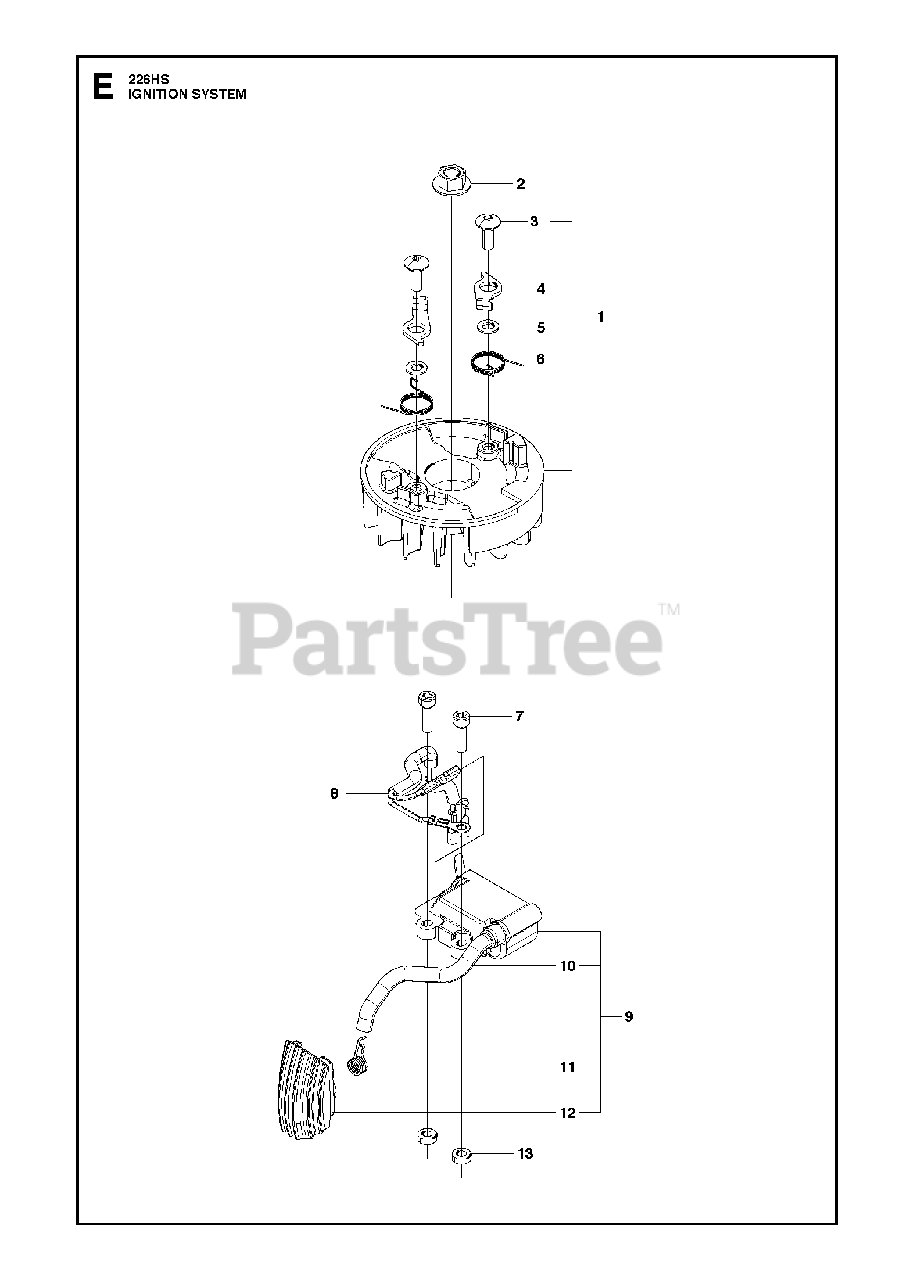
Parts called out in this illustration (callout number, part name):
1	ROTOR ASSY
2	NUT
3	SCREW
4	PAWL
5	WASHER 5X10X10
6	SPRING
9	COIL ASSY
10	CORD
11	SPRING
12	CAP
